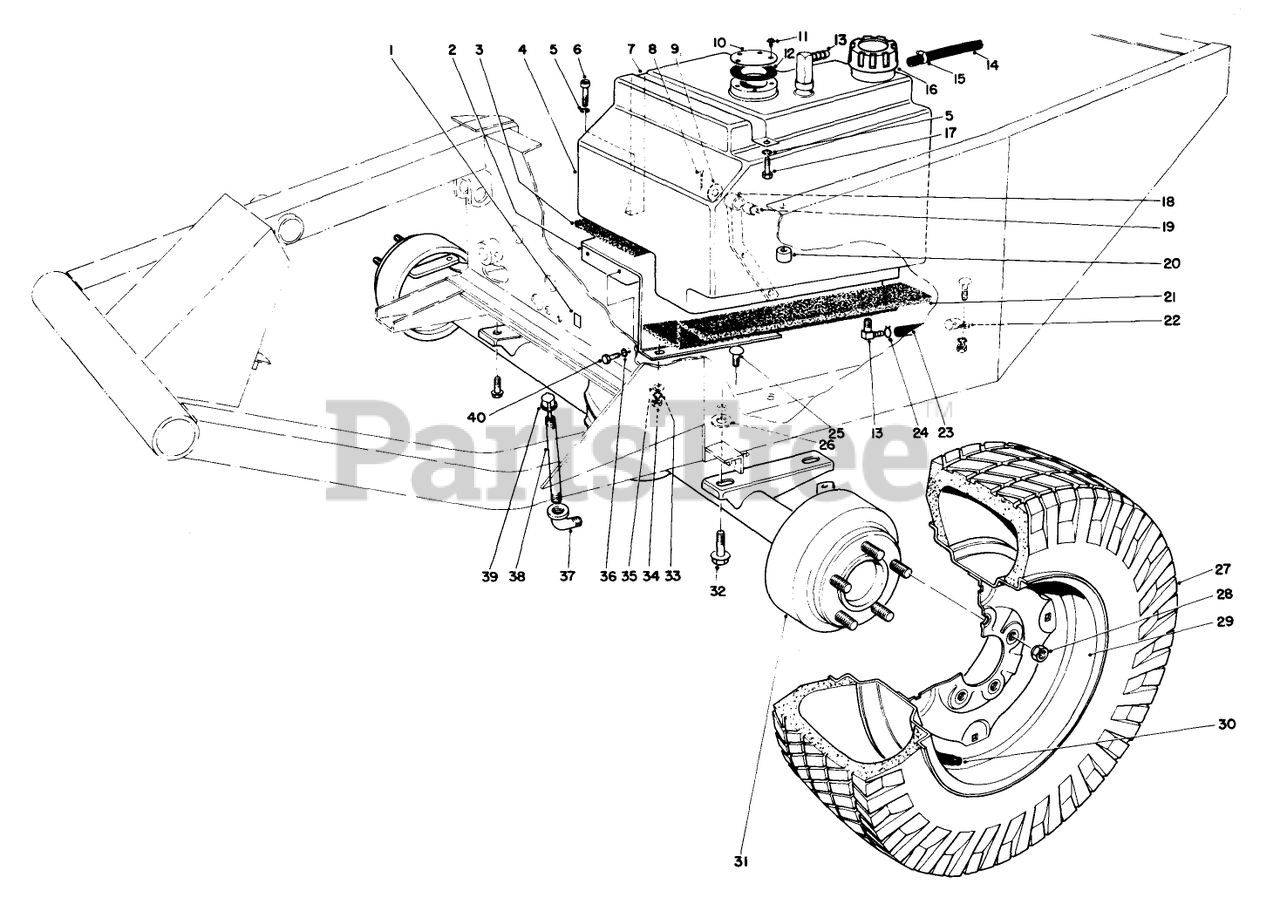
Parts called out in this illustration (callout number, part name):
1	DECAL-OIL
2	GAS TANK BASE WA
3	FOAM-SUPPORT, TANK
4	Gas Tank (Incl. Ref. #13)
5	WASHER-LOCK
6	SCREW-HSH
7	STRAP-TANK, FUEL
8	PIN-COTTER
9	WASHER-THRUST
10	COVER FUEL TANK OPEN
11	SCREW-HWHTF
12	Gasket
13	FITTING-ELBOW, 90 DEG
14	HOSE-FUEL
15	CLAMP-HOSE
16	GAS CAP ASSEMBLY
17	SCREW-HH
18	Steering Link (Incl. Ref. #19)
19	BUSHING
20	SPACER
21	FOAM-SUPPORT, TANK
22	CLAMP-R
23	HOSE-FUEL
24	CLAMP-HOSE
25	BOLT-CARR
26	SHIM-AXLE
28	NUT-LUG
30	STEM-VALVE
31	AXLE WA RO
33	WASHER-LOCK
34	NUT-HEX
35	WASHER-PLAIN
36	WASHER-LOCK
37	FITTING-ELBOW-90
38	NIPPLE-PIPE
39	DIPSTICK ASM
40	SCREW-HH, TAP
